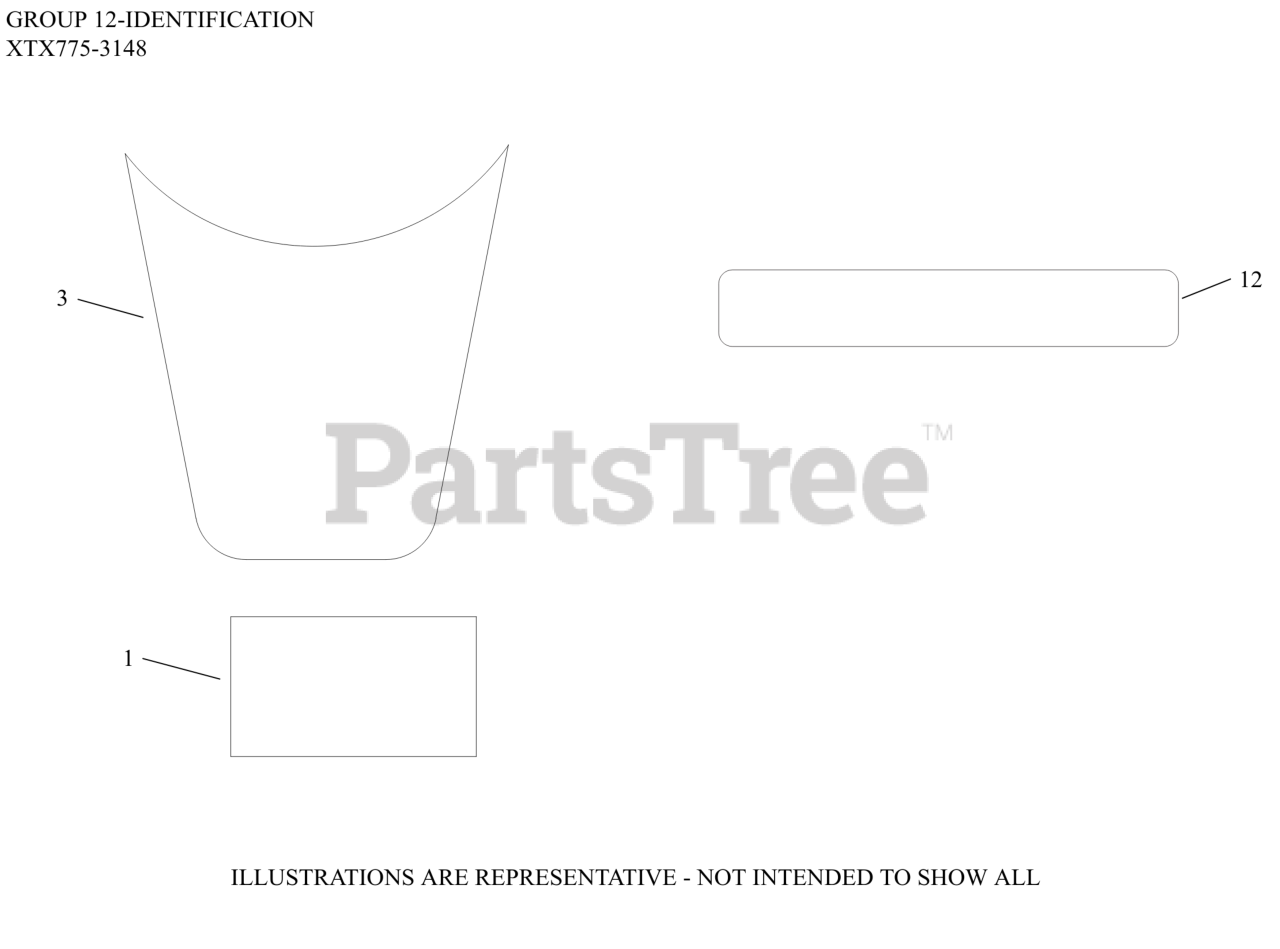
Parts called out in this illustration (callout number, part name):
1	DECAL, WARNING
3	DECAL, XTX775
12	DECAL,STOP/LOW SPD/HIGH SPD/CHOKE
